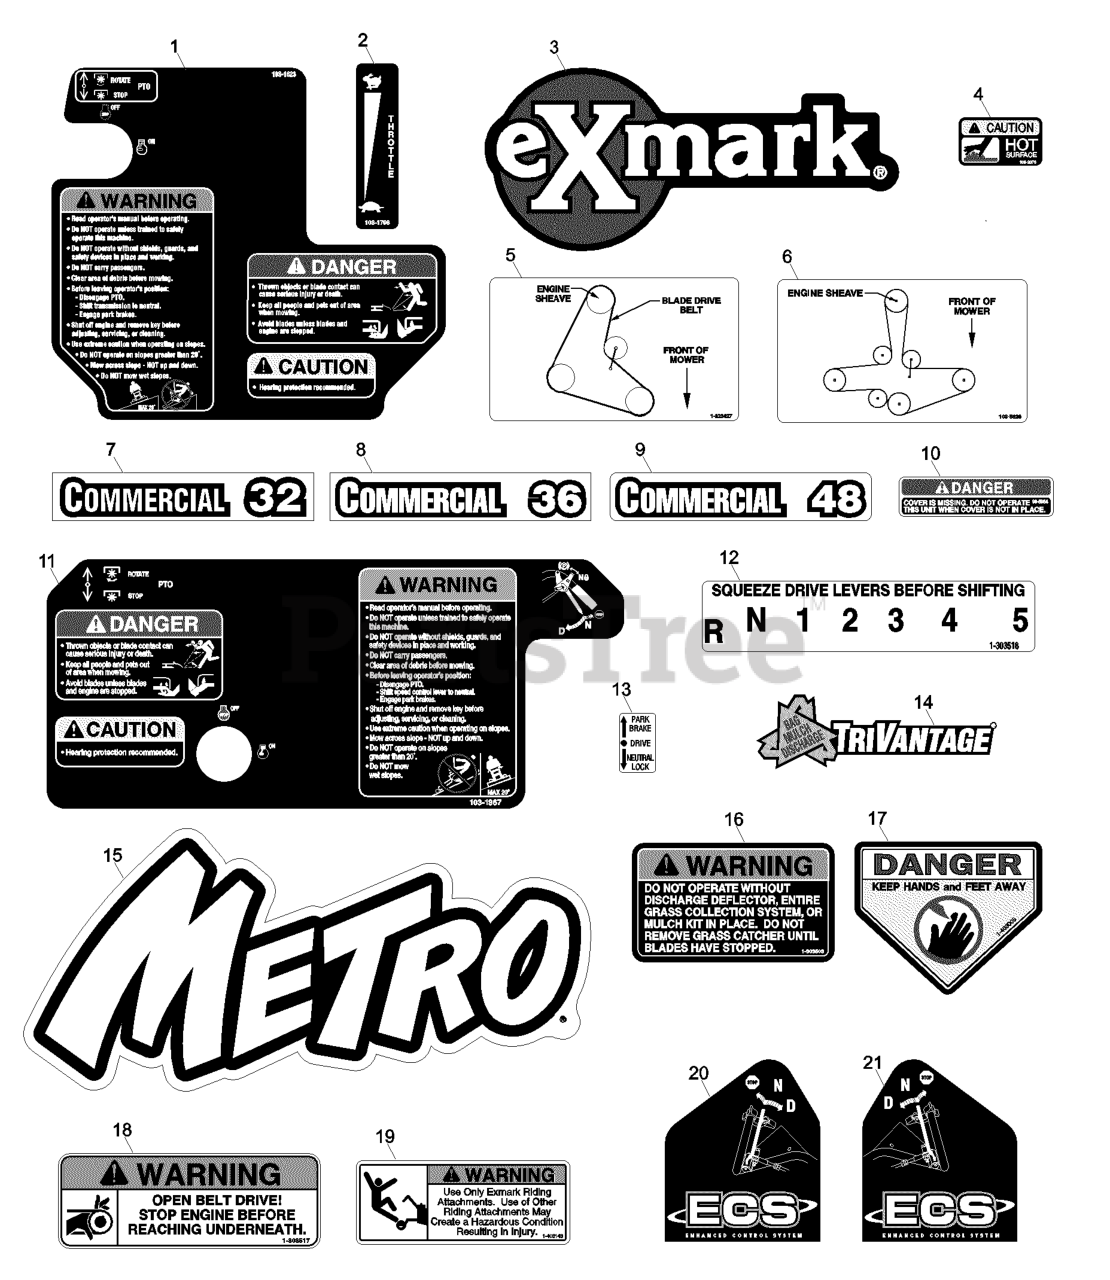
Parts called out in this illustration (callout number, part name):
1	DECAL,METRO ECS CONSOLE
2	DECAL,THROTTLE ONLY
3	DECAL,EXMARK LOGO
4	DECAL-CAUTION
5	DECAL,BELT ROUTING 32/36
6	DECAL,BELT ROUTING
7	DECAL,COMMERCIAL 32
8	DECAL,COMMERCIAL 36
9	DECAL,COMMERCIAL 48
10	DECAL-COVER, MISSING
11	DECAL,CONSOLE
12	DECAL,SHIFTER
13	DECAL,NEUTRAL/BRAKE
15	DECAL,METRO MODEL
16	DECAL-WARNING, DISCHARGE
17	DECAL-DANGER
18	DECAL,BELT DRIVE
19	DECAL,SULKY WARNING
20	DECAL,RH ECS INSTRUCTION
21	DECAL,LH ECS INSTRUCTION
